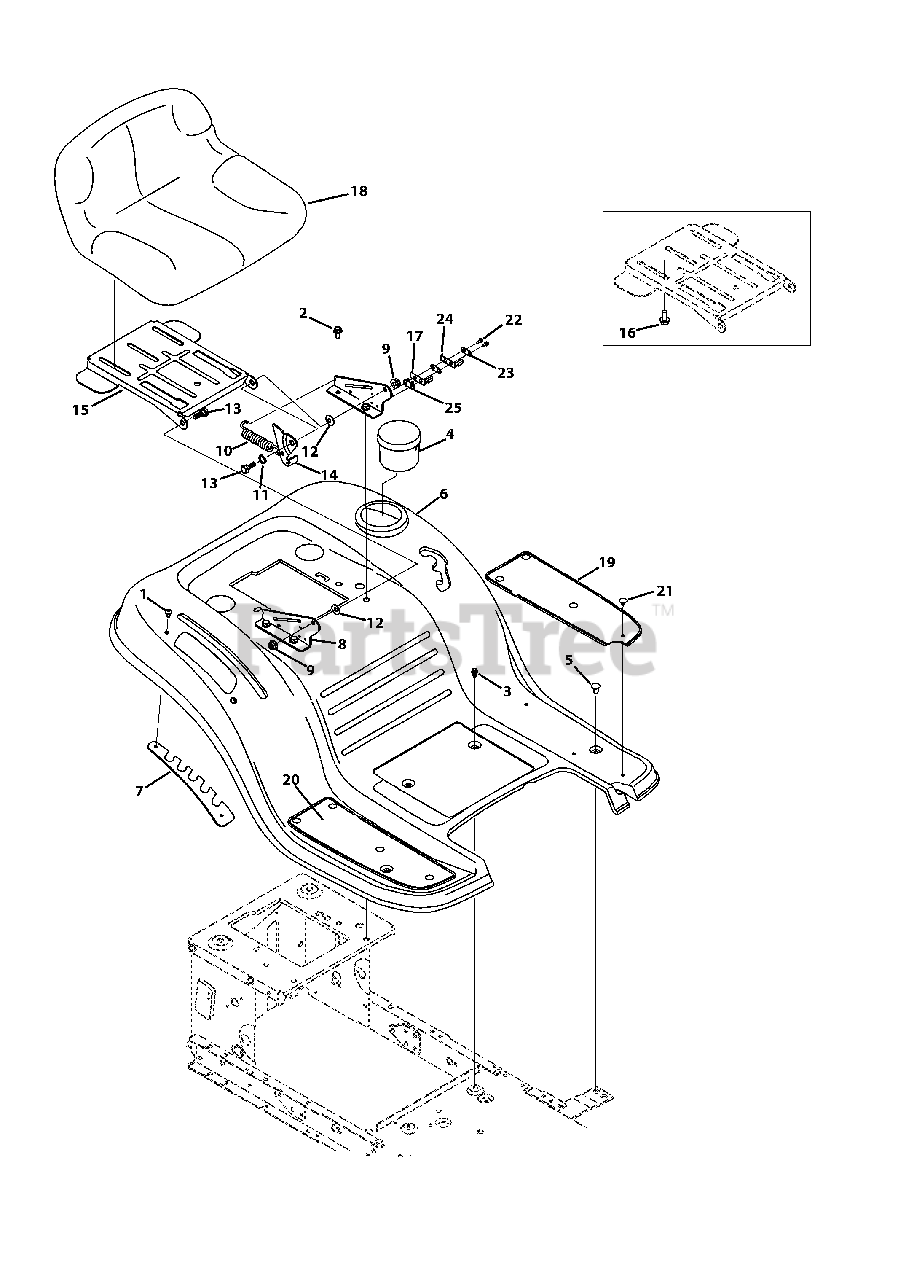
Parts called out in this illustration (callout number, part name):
1	Screw, 1/4-20 x .500
2	Screw, 5/16-18 x .750
3	Screw Pan Torx Head, 1/4-20 x .500
4	Cup Holder
5	Screw Carriage, 1/4-20 x .62
6	Fender - Red
7	Lift Adjuster Bracket
8	Seat Mount Bracket
9	Flangelock Nut, 5/16-18
10	Extension Spring
11	Flat Washer, .510x .750 x .033
12	Bell Washer, .340 x .872 x .060
13	Shoulder Screw, 5/16-18 x .437 x .268
14	Lift Seat Bracket
15	Pivot Seat Manual Adjust Bracket
16	Hex Head Flange, 3/8-16 x .875
17	Inner Seat Spring
18	Med. Back Seat, Black
19	Foot Pad, LH
19	Foot Pad, Abrasive, LH
20	Foot Pad, RH
20	Foot Pad, Abrasive, RH
21	Ratchet Clip, .250 x .500
22	Screw, 8-18 x .500
23	Insulator Plate
24	Outer Seat SPring
25	Insulator Boss Plate
